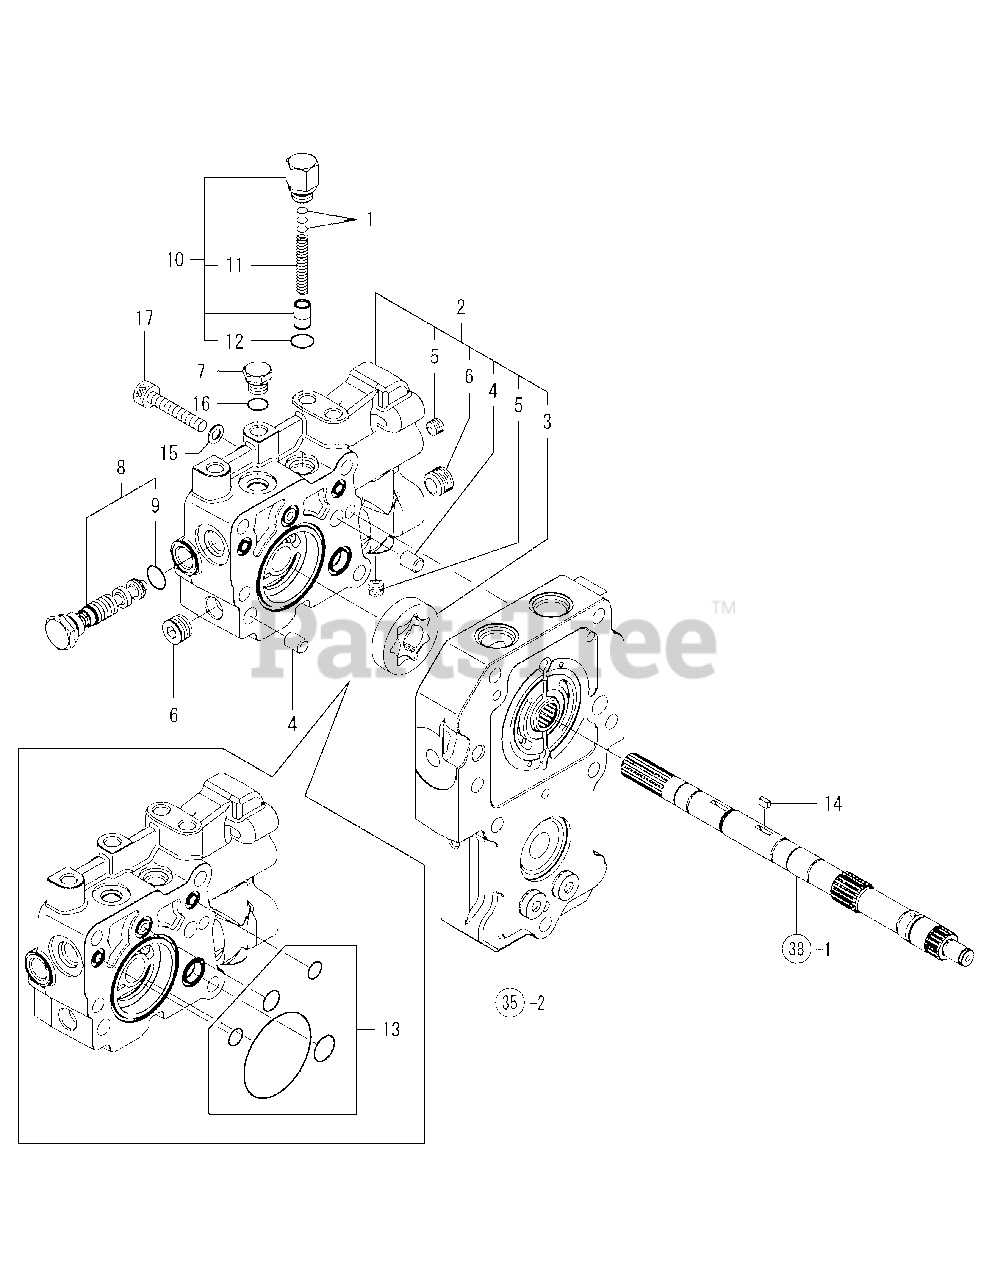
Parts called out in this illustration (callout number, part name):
2	PUMP BODY K93 CMP
4	PARALLEL PIN, M10X12
5	PLUG PT1/8,SCREW
6	PLUG PT3/8,SCREW
7	PLUG 1/2-20 UNF
8	REDUCING VALVE COMP.
9	O-RING 1A P-14.0
10	PRESSURE VALVE COMP.
12	O-RING 1A P-12.0
15	SEAL WASHER 8S
16	PACKING 1A AS 905
